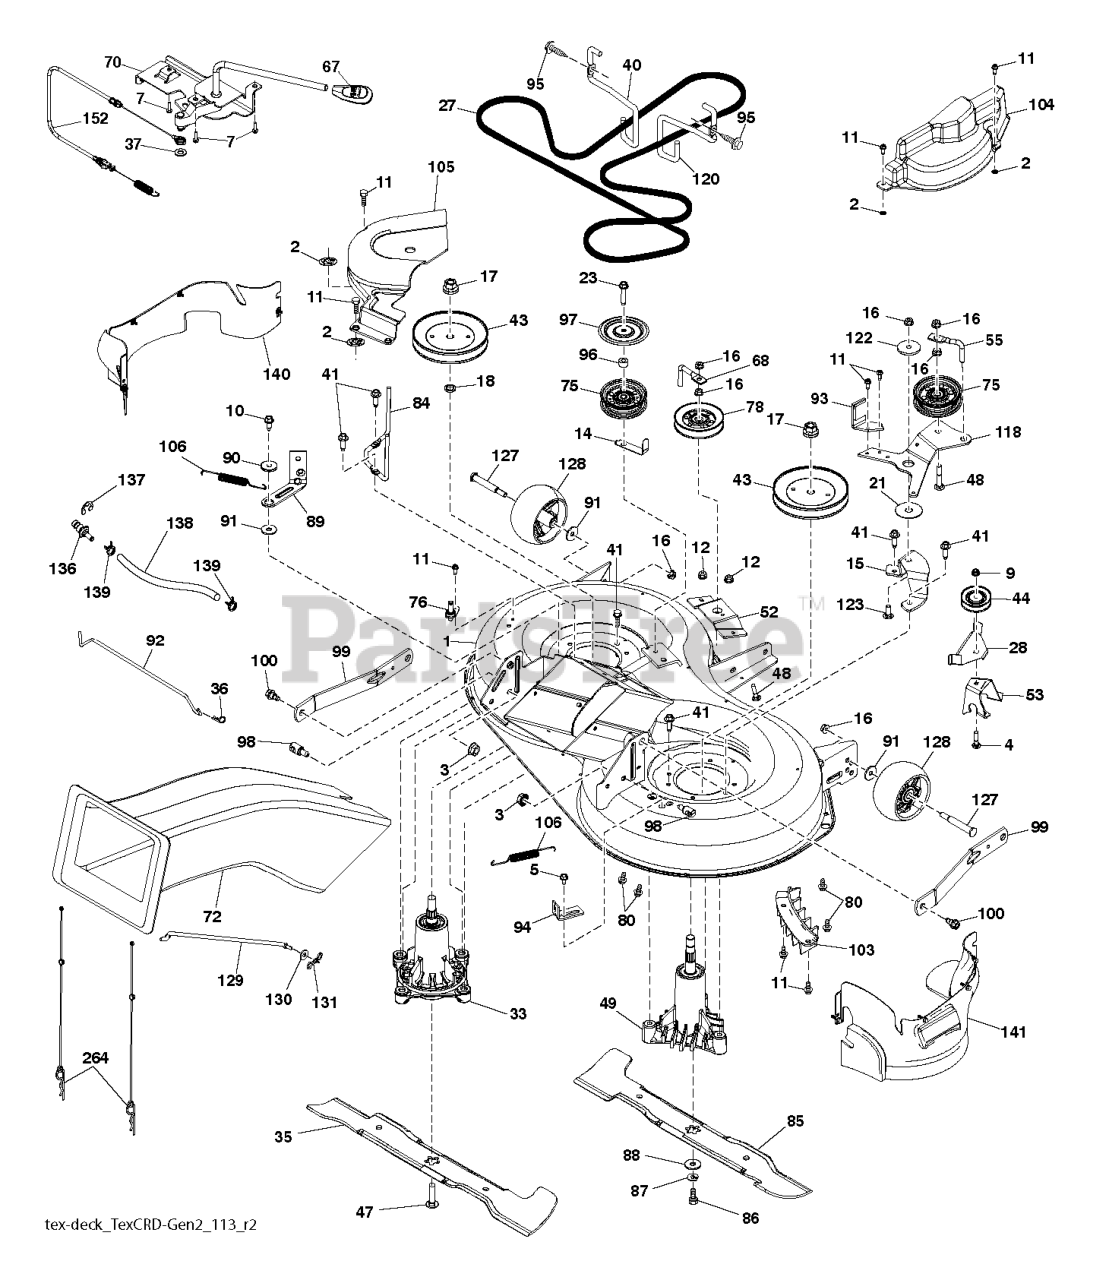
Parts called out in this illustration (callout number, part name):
1	KIT.SVC.DECK.WLD.97CM.TEX.498
2	PALNUT 1/4
3	GSPW Nuts
4	BOLT.CARRIAGE.5/16-18
5	BOLT.5/16HEX.WHS.HD
9	NUT HEX FLG NYLOCK BLK 5_16-1
10	SCREW 3/8-16X1
11	SCREW.1/4-20X5/8
12	NUT HEXAGON FLANGE 5/16-18 ST
14	KEEPER, BELT IDLER
15	BRACKET CRD IDLER ARM MOUNT BL
16	NUT LOCK FLG 3/8-16 UNC
18	WASHER.SPACER.MANDREL
23	BOLT;HEX_3/8-16 X 1.78.CLRZINC
28	KEEPER 97 CRD ANGLED IDLER KEE
33	KIT.MANDREL.NONGREASE.TALL
35	BLADE.3N1.LH.CRD.97
36	RETAINER M
37	WASHER PLAIN WASHER 3/8 X 0.08
40	KEEPER BELT ENGINE LH
41	BOLT.HEX.WASHR.HED.313-18X1.19
43	PULLEY.MANDREL.5.438.PD
44	PULLEY.V-IDLER.
47	SCREW.SEMS.7/16-20X1.HEX.HEAD
49	MANDREL ASM.CRD RH 6PT STAR
53	BRACKET 97 CRD ANGLED V-IDLER
67	HANDLE.CLUTCH.CABLE.LT
70	CLUTCH.ASM.MANUAL.YT.PREDATORQ
72	CHUTE.SLOTTED.HOLES.TEX.CRD.II
76	1/2" BARB.DECK.WASHOUT.PORT
78	REPL BY 532 1467-63
80	GSPW Bolts
84	KEEPER.BLT.PNT.MNDRL.PULL.6.25
85	BLADE.3N1.RH.CRD.97
86	BOLT.3/8-24X1.25GR8. LHTHRD
88	WASHER.BLADE
89	ARM.BRAKE.97.LH
90	SPACER.RETAINER
92	LINK 97 CRD MANUAL DRIVE BRAKE
93	BRAKE CRD RH BRAKE ARM BLACK E
94	BRKT.CLUTCH.CABLE
95	SCREW, 3/8-16X3/4
96	SPACER
97	PROTECTOR
98	STUD.W/"D"ANTI-ROTATION
99	ARM.SUSPENSION.MOWER.R
100	BOLT.SHOULDER
103	GUARD GUARD FRONT VENT
104	GUARD 97CRD RH MANDREL COVER;
105	MANDREL MANDREL COVER LH
106	SPRING.BRAKE.RETURN.38"
120	KEEPER BELT RH
122	SPACER.RETAINER.MOWER
128	WHEEL.GAUGE.RALLY
129	ROD ROD. SWAY CRD GEN II
131	PIN.COTTER.5/16.BOW TI
136	PLUG WASHOUT PORT HOOKUP
138	HOSE.3/8ID.BULK.12"
140	GUARD.ASM.LH.CRD.FRENCH.97CM
141	GUARD.ASM.RH.CRD.FR.97CM.SLOT
152	CABLE CABLE CLUTCH MANUAL W/S
